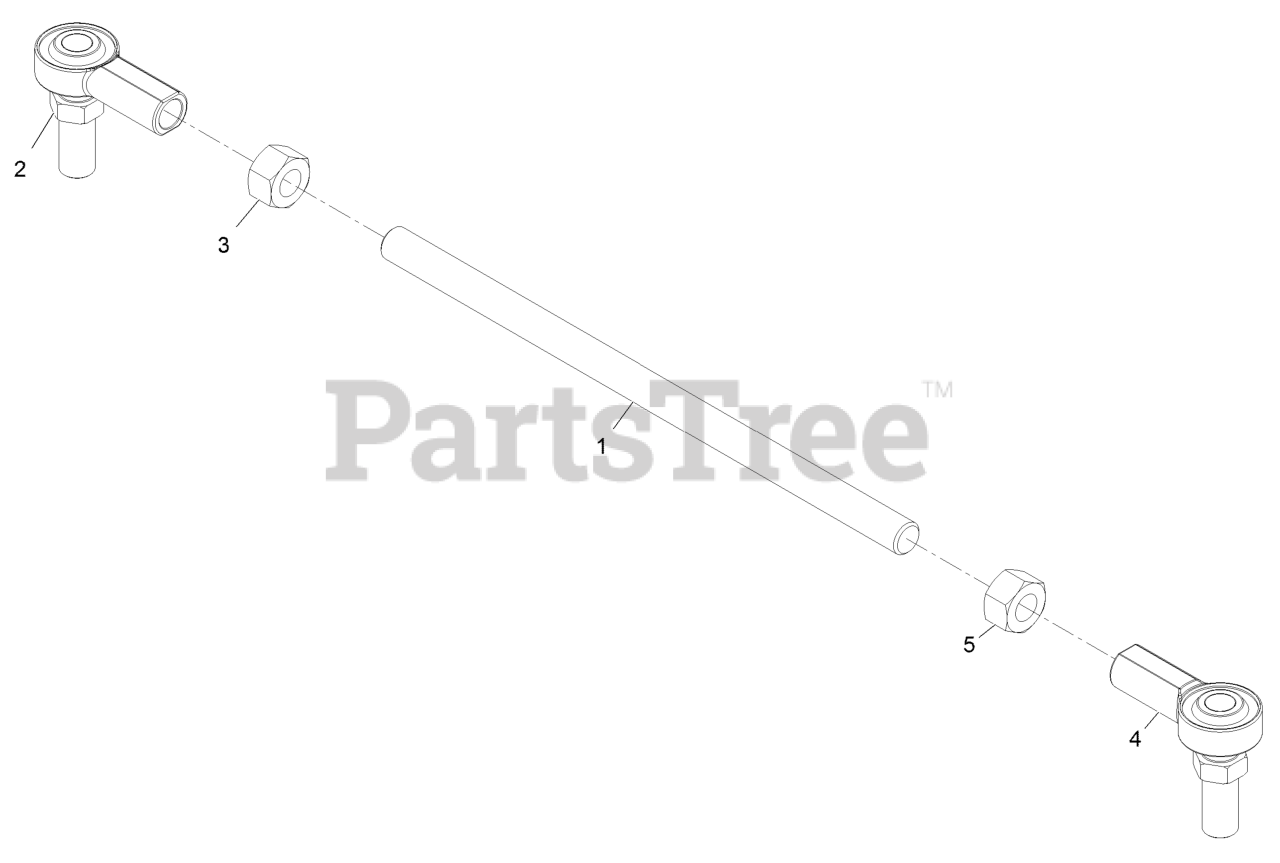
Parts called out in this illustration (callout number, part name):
2	ROD-END, RH
3	NUT-HEX
4	ROD-END, LH
5	NUT-HEX, LH
